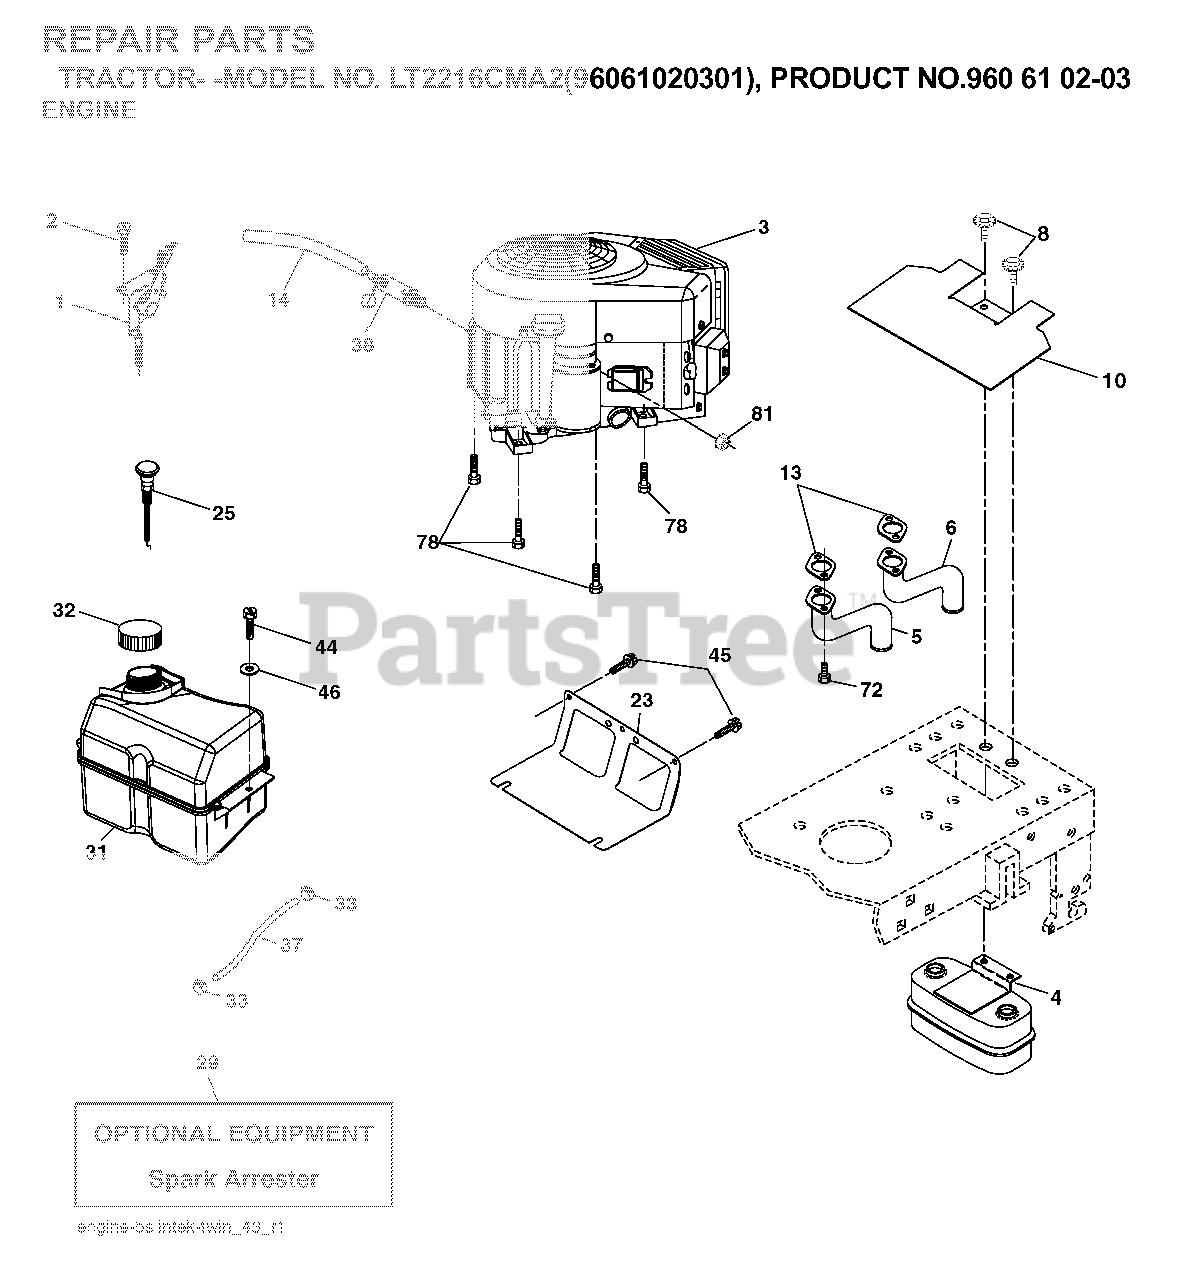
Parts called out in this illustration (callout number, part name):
1	CONTROL, THROTTLE
2	SCREW
4	MUFFLER.TWIN.CYL.LOW.TONE
5	TUBE MANIFOLD LH
6	EXHAUST TUBE RH
8	BOLT, 5/16-18 X 1 3/4
10	RP SHIELD HEAT MUFFLER
13	GASKET.MUFFLER
14	TUBE, DRAIN OIL ASM.
23	SHEILD.BROWNING.DBR.GUARD
29	ARRESTER SPARK (OPTIONAL)
31	TANK FUEL
32	FUEL CAP
33	HOSE CLAMP
37	LINE.FUEL.20
38	PLUG DRAIN OIL EASY
44	SCREW HEXWSHR 1/4-20X3/4
45	SCREW, 3/8-16X3/4
72	SCREW.SOCKET.HEAD.5/16-18
78	SCREW.3/8-16
81	NUT
